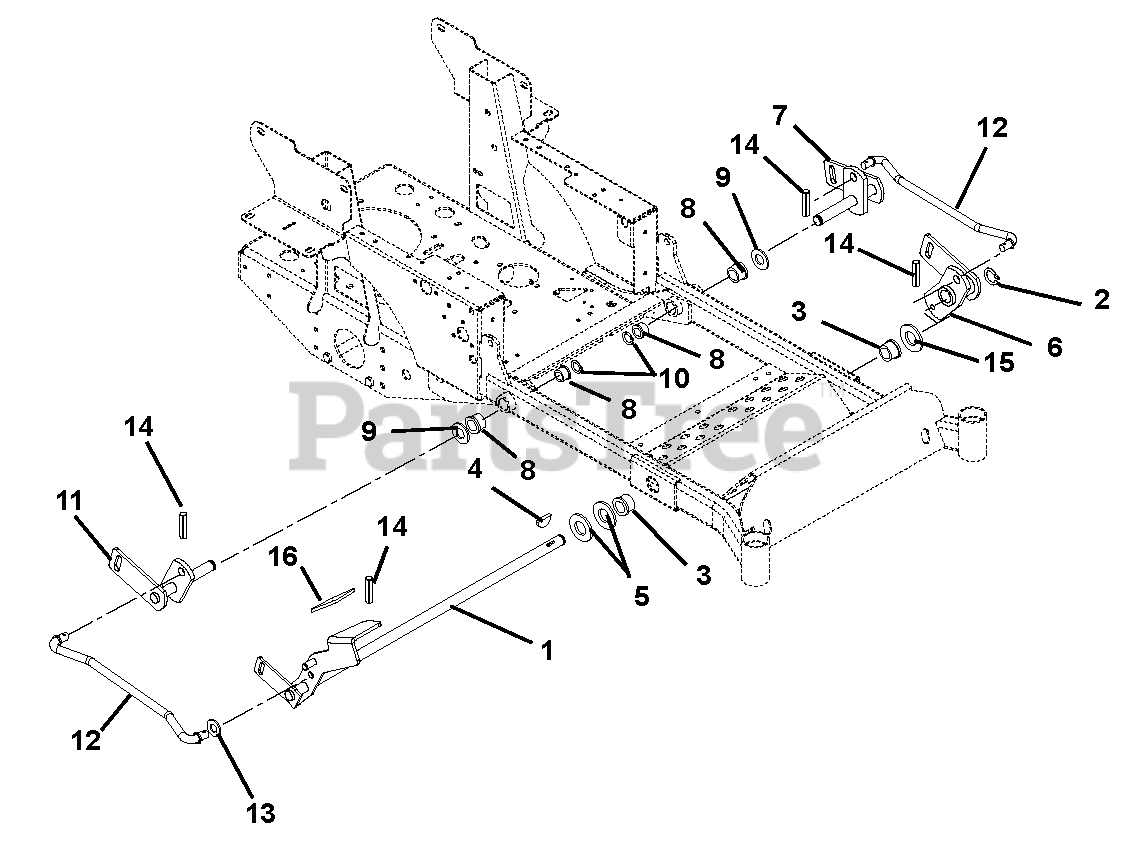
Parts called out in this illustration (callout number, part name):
1	Weldment, Mechanical Deck Lift
2	Ring, Retaining External 1.00 x .078
3	Bushing, Flange Nylon 1.020 x 1.385 x .75 x 1.75
4	Key, Woodruff .25 x 1.00
5	Washer, Flat Steel 1.062 x 2.0 x .134
6	Weldment, Left Hand Mower Lift Arm
7	Weldment, Left Hand Rear Mower Lift Arm
8	Bushing, Flange Nylon .762 x 1.0 x .580 x 1.48
9	Washer, Hardened Steel .758 x 1.23 x .031
10	Ring, Retaining External .689 x .077
11	Weldment, Right Hand Rear Mower Lift Arm
12	Rod, Lift Assist
13	Washer, Flat Steel .630 x 1.25 x .062
14	Pin, Roll .25 x 1.25 Stainless Steel
15	Washer, Hardened Thrust 1.00 x 1.55 x .03
16	Grip, Pedal
